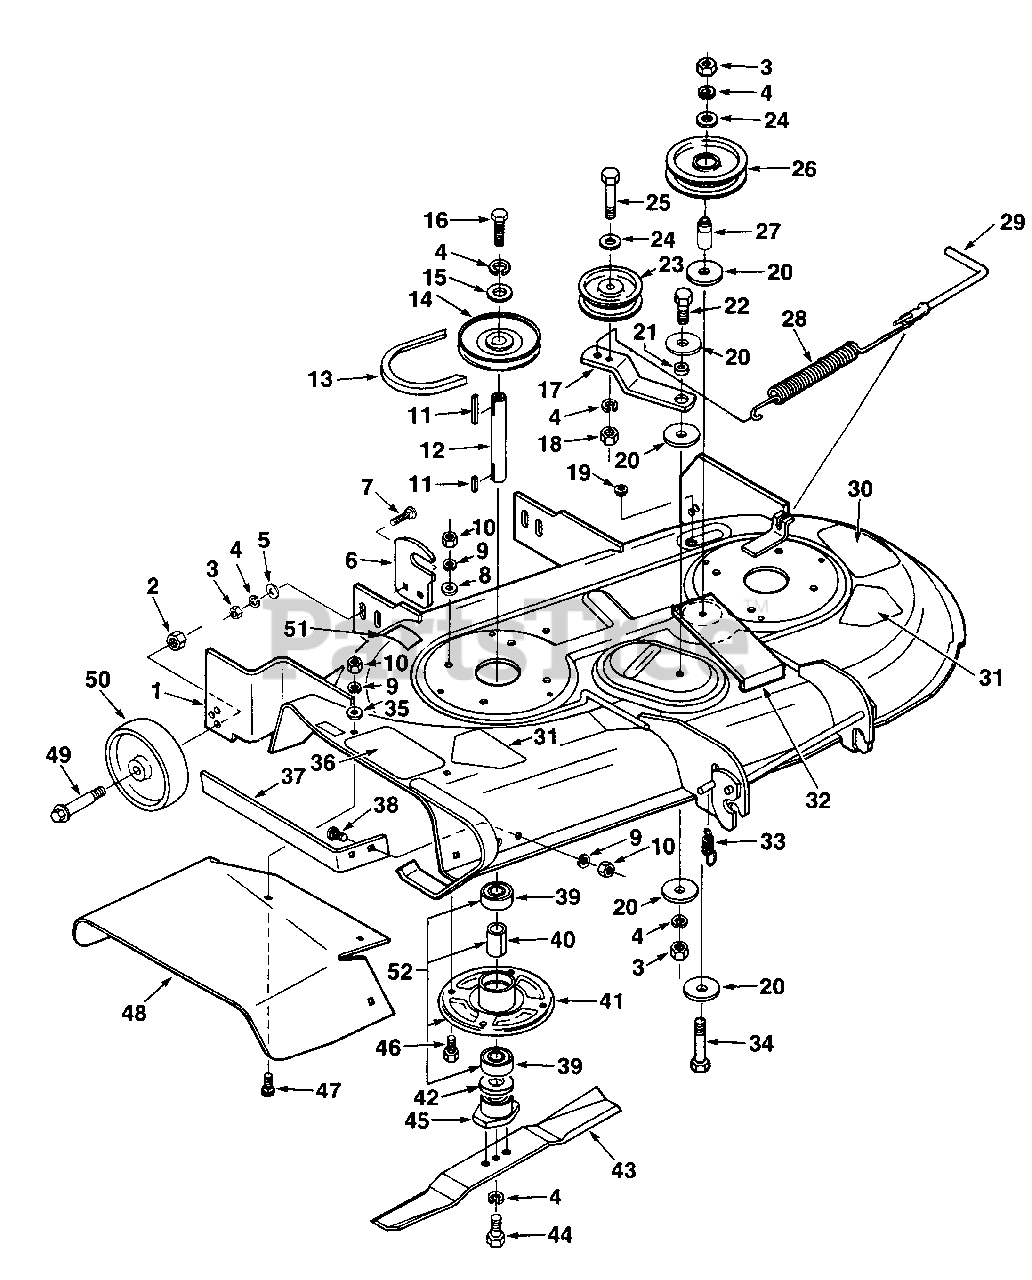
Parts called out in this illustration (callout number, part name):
1	MOWER HOUSING ASSEMBLY
2	NUT- 3/8-16 Prev. tq. hex L' nut
3	NUT- 3/8-16 Hex
4	WASHER- Lock 3/8 heavy
6	BRACKET- Rear hanger
7	BOLT- 3/8-16 x 3/4 rd. hd. sq. neck Carr
8	WASHER- 5/16 std. Flat
9	WASHER- Lock 5/16 hvy.
10	NUT- 5/16-18 Hex
11	KEY- 3/16 x 13/16 parallel
12	CUTTER- Shaft
13	BELT- Cutter drive
14	PULLEY- Mower drive
15	WASHER- Pulley retainer
16	SCREW- 3/8-24 x 2 1/4 hex hd.
17	ARM- Idler
18	NUT- 3/8-16 hex jam
19	FITTING- Wash out
20	WASHER- Blade mtg.
21	SPACER- Idler arm pivot
22	SCREW- 3/8-16 x 1 1/4 hex hd.
23	PULLEY- Idler
24	WASHER- 3/8 flat
25	SCREW- 3/8-16 x 2 Hex hd.
26	IDLER PULLEY ASSEMBLY
27	MOUNTING- Spacer idler
28	SPRING- Extension
29	ROD- Spring release
30	DECAL- Danger
31	DECAL- CPSC warning
32	SUPPORT- Idler
33	SPRING- Hinge latch, front
34	SCREW- 3/8-16 x 3 hex hd.
35	WASHER- 5/16 SAE flat
36	DECAL- Danger
37	GUARD- Toe
38	BOLT- 5/16-18 x 7/8 rd. hd. short sq.
39	BEARING- Cutter shaft
40	SPACER- Bearing
41	CUTTER HOUSING ASSEMBLY
42	WASHER- Flat
43	CUTTER BAR SET
44	SCREW- 3/8-24 x 1 hex SAE Grade 8
45	BLADE- Adapter
46	SCREW- 5/16-18 x 3/4 hex hd
47	BOLT- 5/16-18 x 5/8 sq. neck carr
48	EXTENSION- Chute
49	BOLT- Shoulder axle
50	WHEEL- Gauge
51	DECAL- Belt mtg. instruction
52	CUTTER- Spindle
